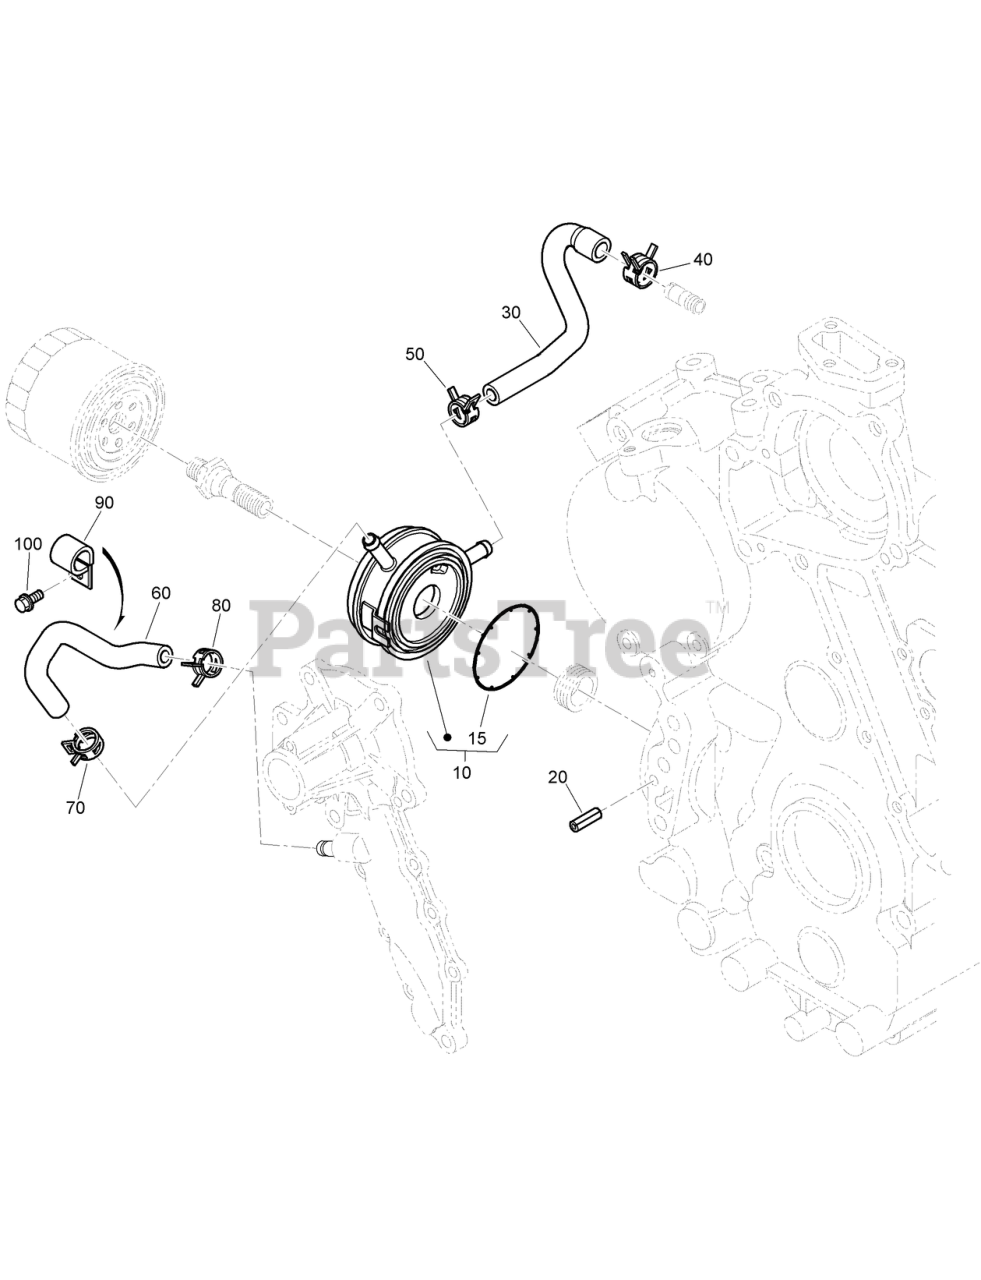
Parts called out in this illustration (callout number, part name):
10	OIL COOLER ASM
15	PACKING
20	PIN-ROLLER
30	HOSE-COOLER, OIL
40	CLAMP-HOSE
50	BAND-PIPE
60	HOSE-COOLER, OIL
70	BAND-PIPE
80	BAND-PIPE
100	BOLT-FLANGE
